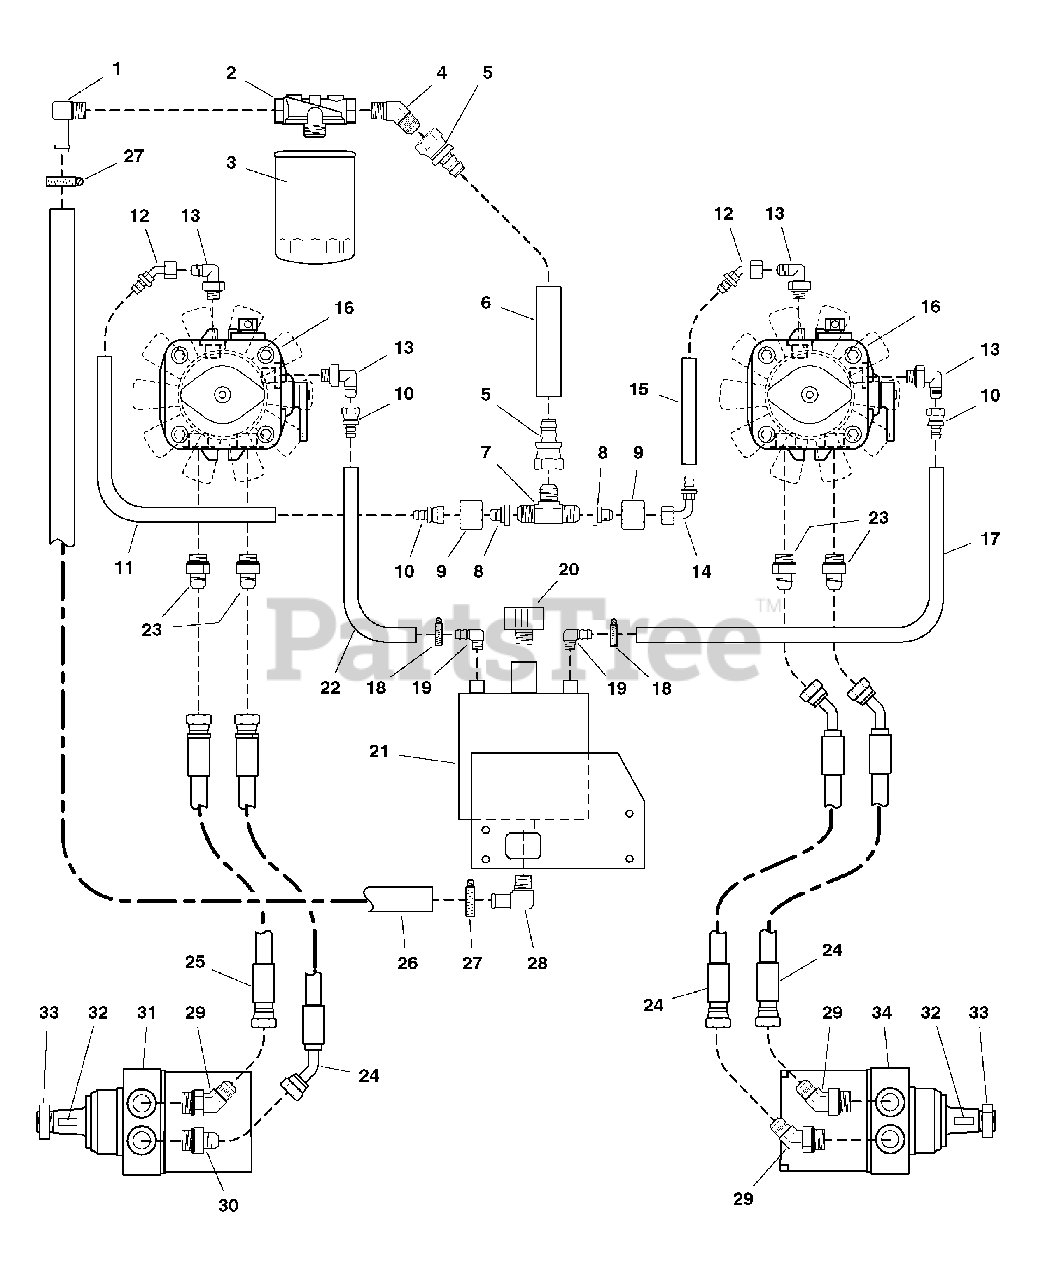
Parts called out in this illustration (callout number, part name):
1	FITTING, 1/2" NPT, 90 Deg.
2	FILTER HEAD
4	FITTING, 1/2" NPT, 45 Deg.
5	FITTING, Hydraulic, Straight Swivel
6	HOSE, Hydraulic, 7-1/2"
7	FITTING, Tee
8	ADAPTER, Tee
9	NUT, Adapter
10	FITTING, Hydraulic, Straight Swivel
11	HOSE, Hydraulic, 13-3/4"
12	FITTING, Hydraulic, 45 Deg. Swivel
13	FITTING, Hydraulic, O-Ring, 90 Deg.
14	FITTING, Hydraulic, 90 Deg. Swivel
15	HOSE, Hydraulic, 6-3/4"
16	HYDRAULIC PUMP w/ FAN
17	HOSE, Hydraulic, 29"
18	HOSE CLAMP, #6
19	FITTING, 1/4" NPT, 90 Deg.
21	HYDRAULIC RESERVOIR
22	HOSE, Hydraulic, 20"
23	FITTING, Hydraulic, O-Ring Adapter
24	HYDRAULIC HOSE ASSEMBLY, 25"
25	HYDRAULIC HOSE ASSEMBLY, 21"
26	HOSE, Hydraulic, 16-1/2"
27	HOSE CLAMP, #10
28	FITTING, 1/2" NPT, 90 Deg.
29	FITTING, Hydraulic, O-RIng, 45 Deg.
30	FITTING, Hydraulic, O-Ring Adapter
31	HYDRAULIC WHEEL MOTOR-LEFT, Complete (includes Ref 32 & 33)
33	CASTLE NUT & COTTER PIN
34	HYDRAULIC WHEEL MOTOR-RIGHT, Complete (includes Ref 32 & 33)
